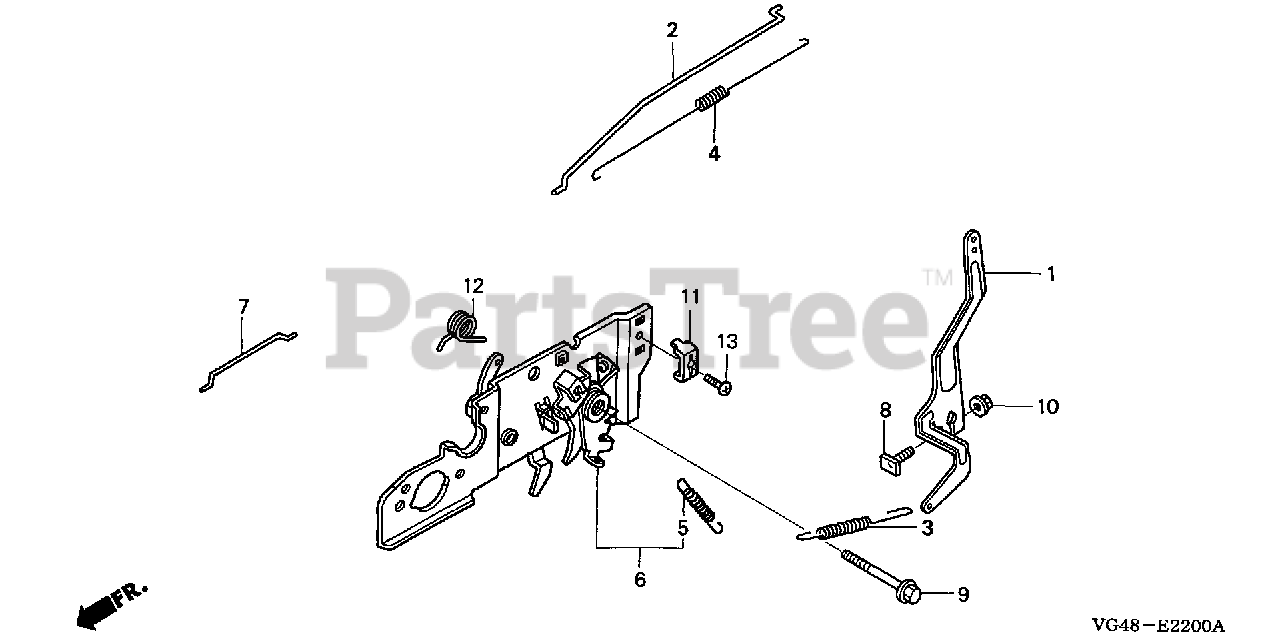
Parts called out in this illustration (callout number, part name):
1	ARM, GOVERNOR
2	ROD, GOVERNOR
3	SPRING, GOVERNOR
4	SPRING, THROTTLE RETURN
5	SPRING, LEVER
6	BASE, CONTROL
7	ROD, CHOKE
8	BOLT, GOVERNOR ARM
9	BOLT, FLANGE (6X45) (CT200)
10	NUT, FLANGE (6MM)
